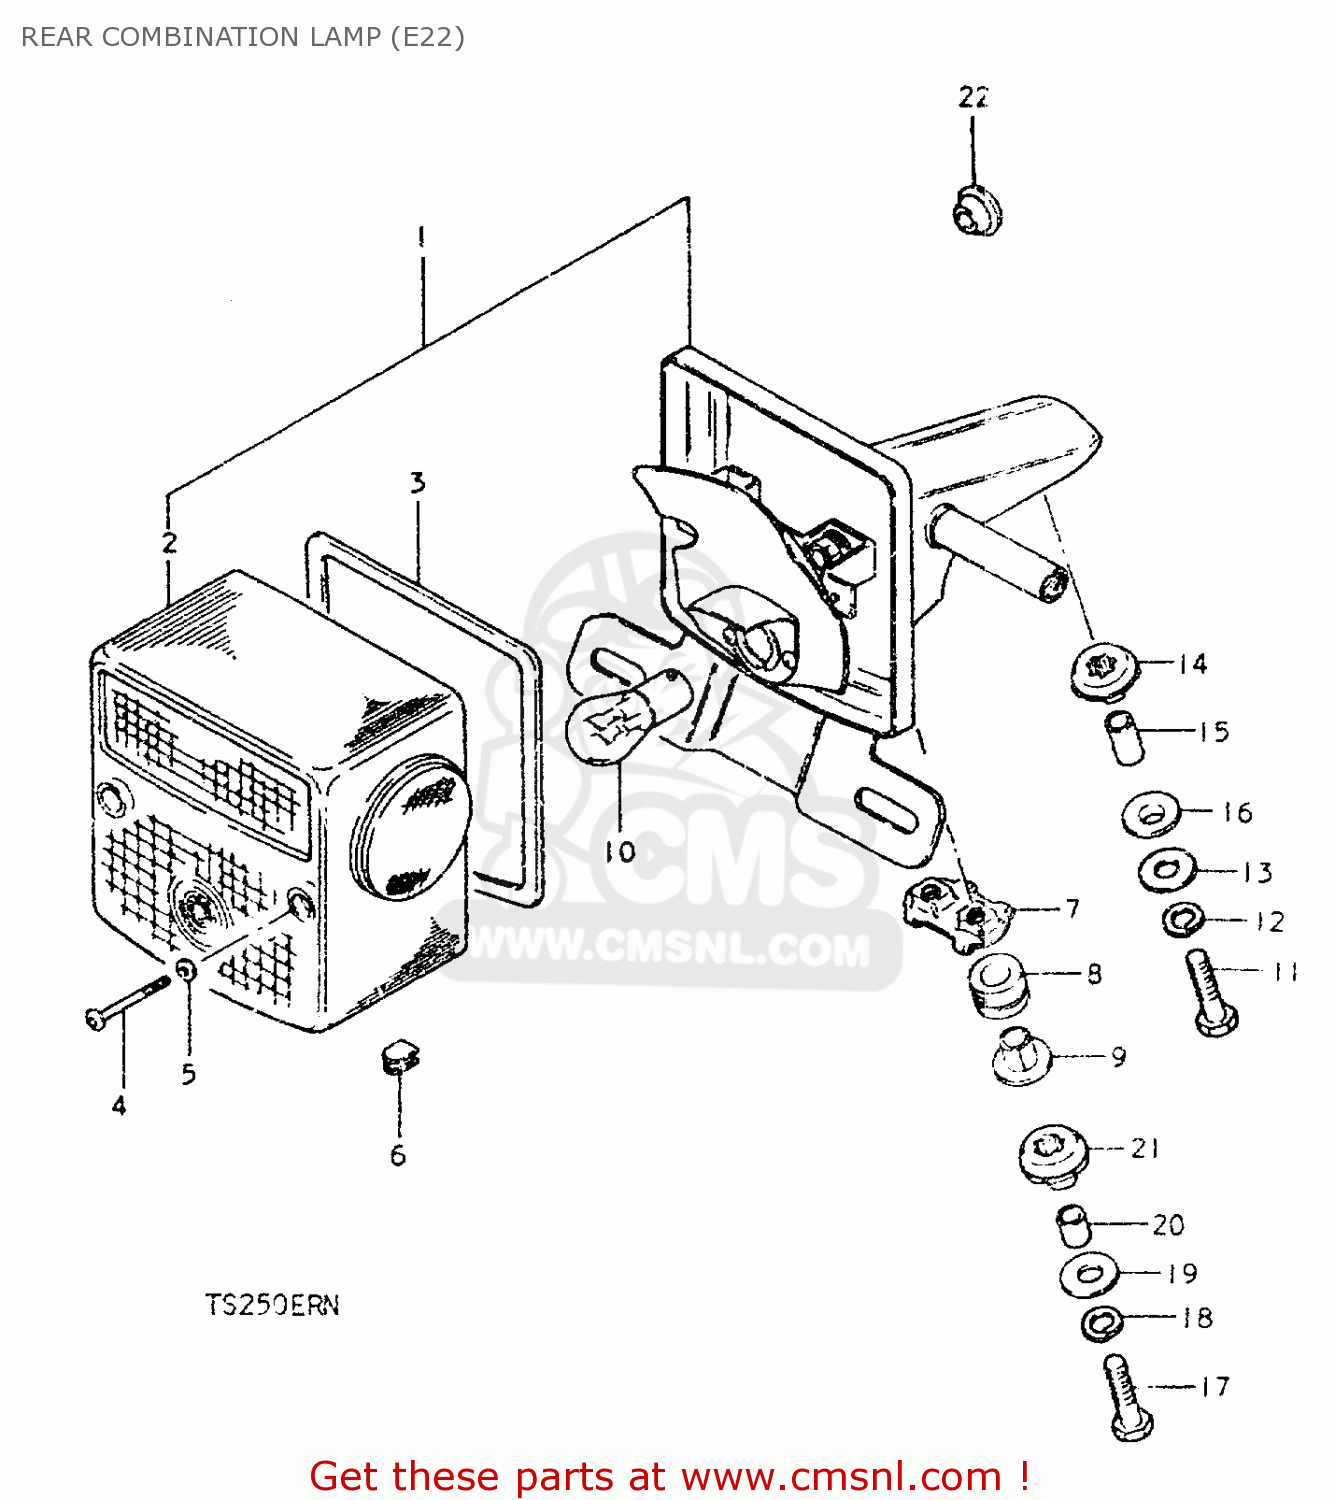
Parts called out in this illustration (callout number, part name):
1	LAMP ASSY, REAR COMBINATION
2	LENS
3	GASKET (NAS)
4	SCREW (4X55)
5	GASKET (NAS)
6	GROMMET,REAR COMBINATION LAMP
7	PLATE
8	CUSHION
9	SPACER
10	BULB (6V,21/5W)
11	BOLT
12	LOCK WASHER
13	WASHER (6.5X20X1.2)
14	CUSHION
15	SPACER
16	CUSHION
17	BOLT
18	LOCK WASHER
19	WASHER (6.5X20X1.2)
20	SPACER
21	CUSHION
22	GROMMET
